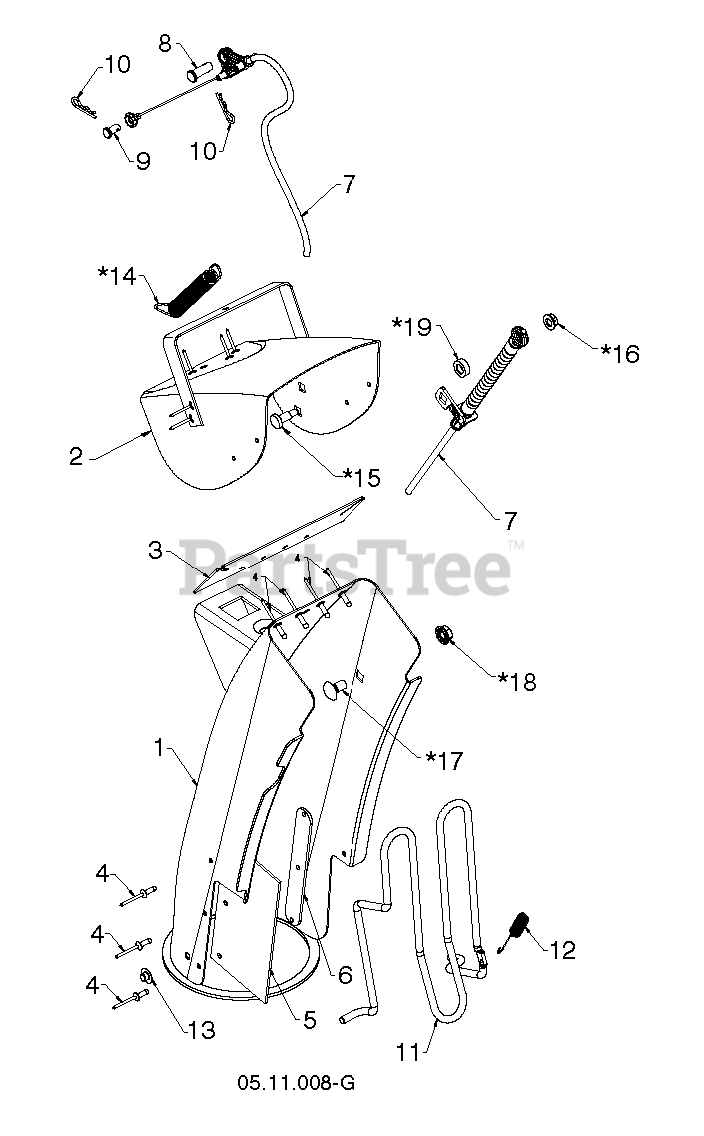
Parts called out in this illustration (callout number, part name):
1	ASM.CHUTE/DEFLECTOR.668
7	CABLE CONTROL.CHUTE.DEFLECTOR.
8	PIN CLEVIS 5/16X.875
9	PIN CLEVIS .25 X .31
10	HAIRPIN.SOFT.ZINC.059X1.125
11	GUARD ROD CHUTE GUARD SHORT CL
12	SPRING.CHUTE.GUARD
13	NUT
